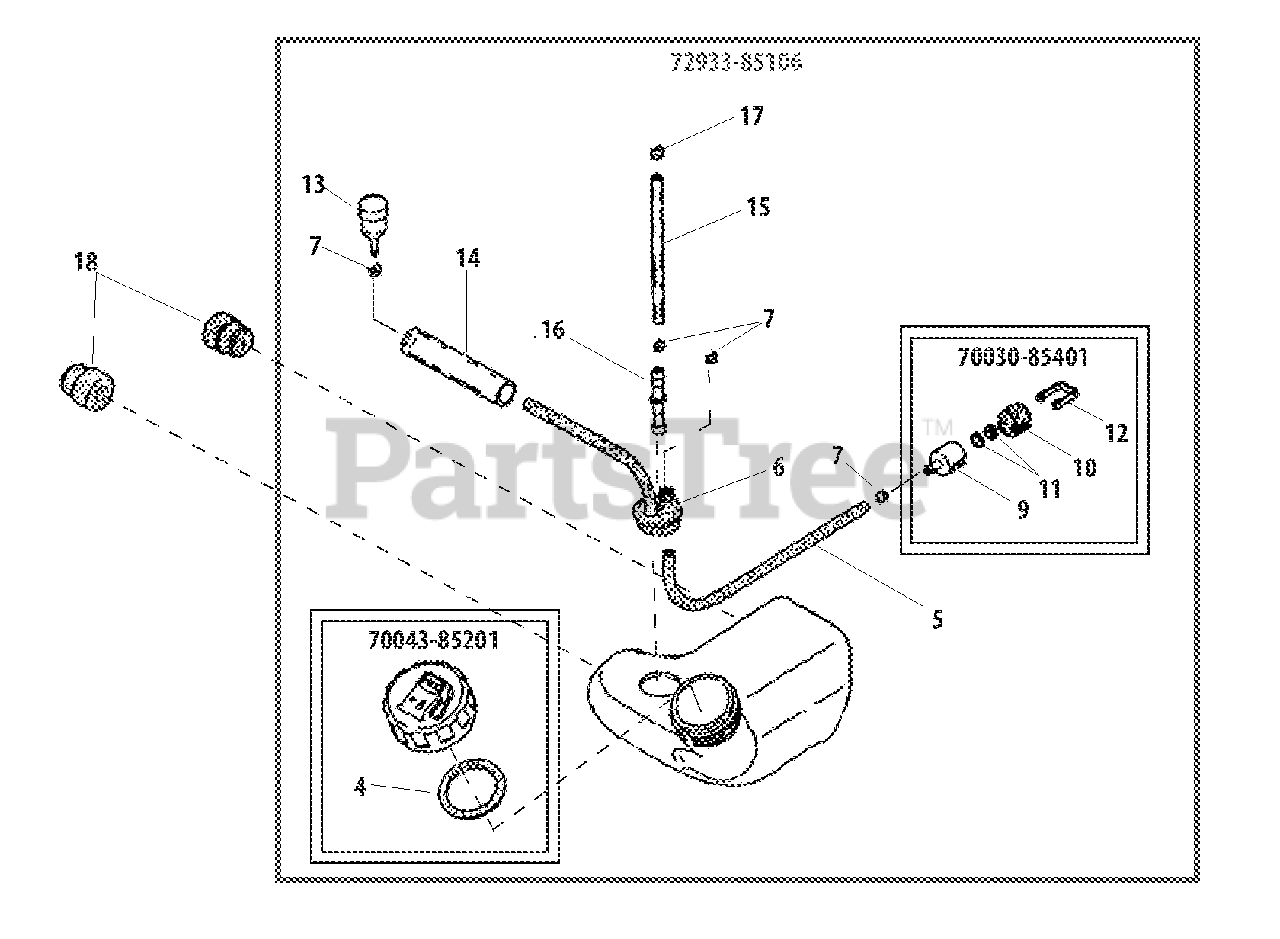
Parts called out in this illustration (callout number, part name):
4	GASKET, CAP
5	PIPE
6	PIPE ASSY
7	RING, RETAINING - 6
9	WEIGHT, FUEL FILTER
10	ELEMENT, FILTER - LARGE
11	STRAINER - SMALL
13	VENT, FUEL TANK
14	VENT PIPE ASSY
15	PIPE - RETURN
16	CONNECTOR, PIPE
17	CLIP - SPRING
18	CUSHION
70030-85401	FUEL FILTER ASSY
70043-85201	CAP ASSY
72933-85106	FUEL TANK ASSY
